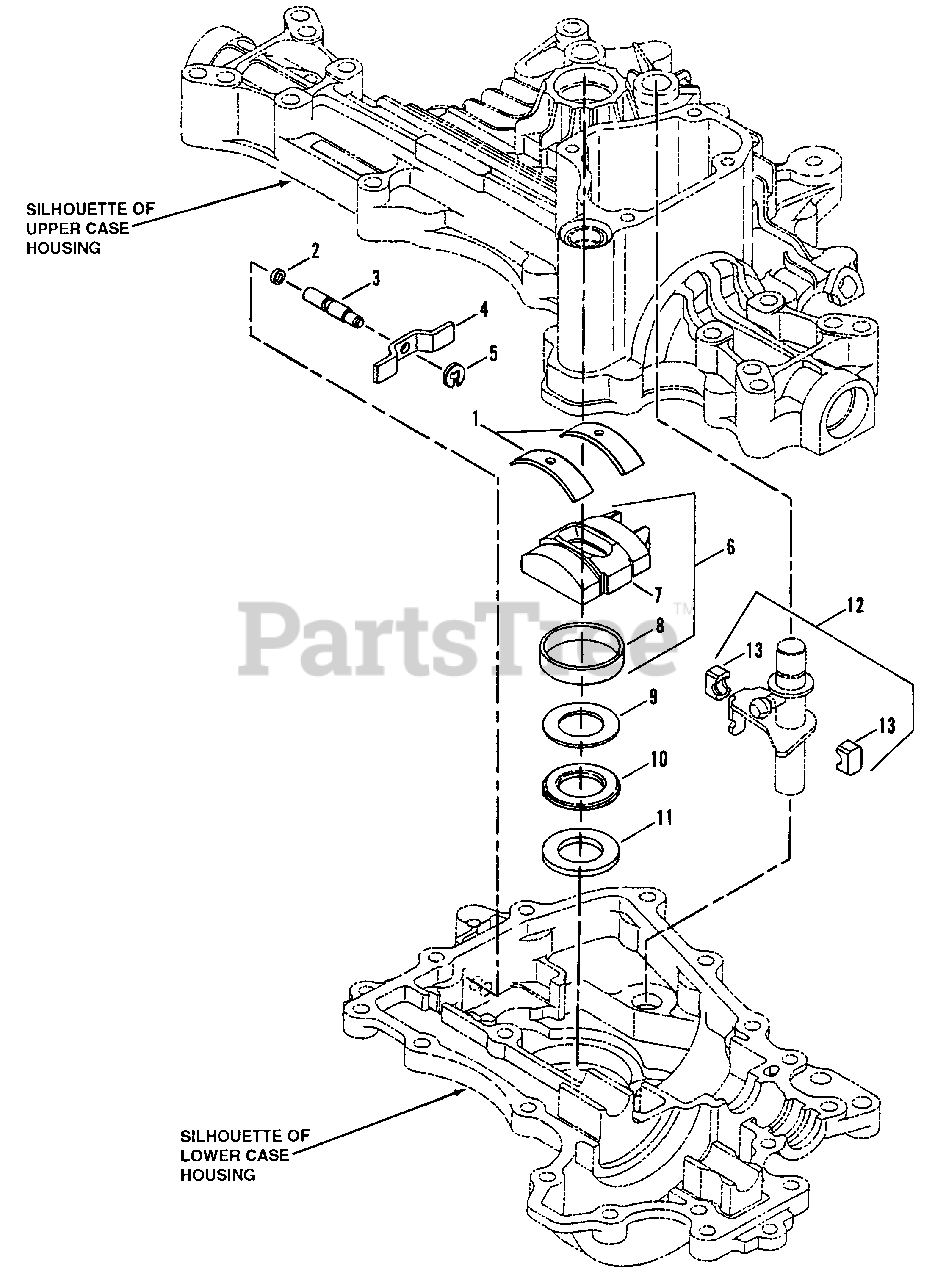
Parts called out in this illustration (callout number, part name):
1	BUSHING, Thrust, Pump Swashplate
3	PIN, Actuating, Transport By-pass Valve
4	BRACKET, Actuating Pin
6	ASSEMBLY, Pump Swashplate
7	SWASHPLATE, Pump
8	BUSHING, Swashplate
9	THRUST-PLATE
10	BEARING, Swashplate
11	THRUST-PLATE
12	ASSEMBLY, Shifter Shaft
13	BLOCK, Shifter Shaft
